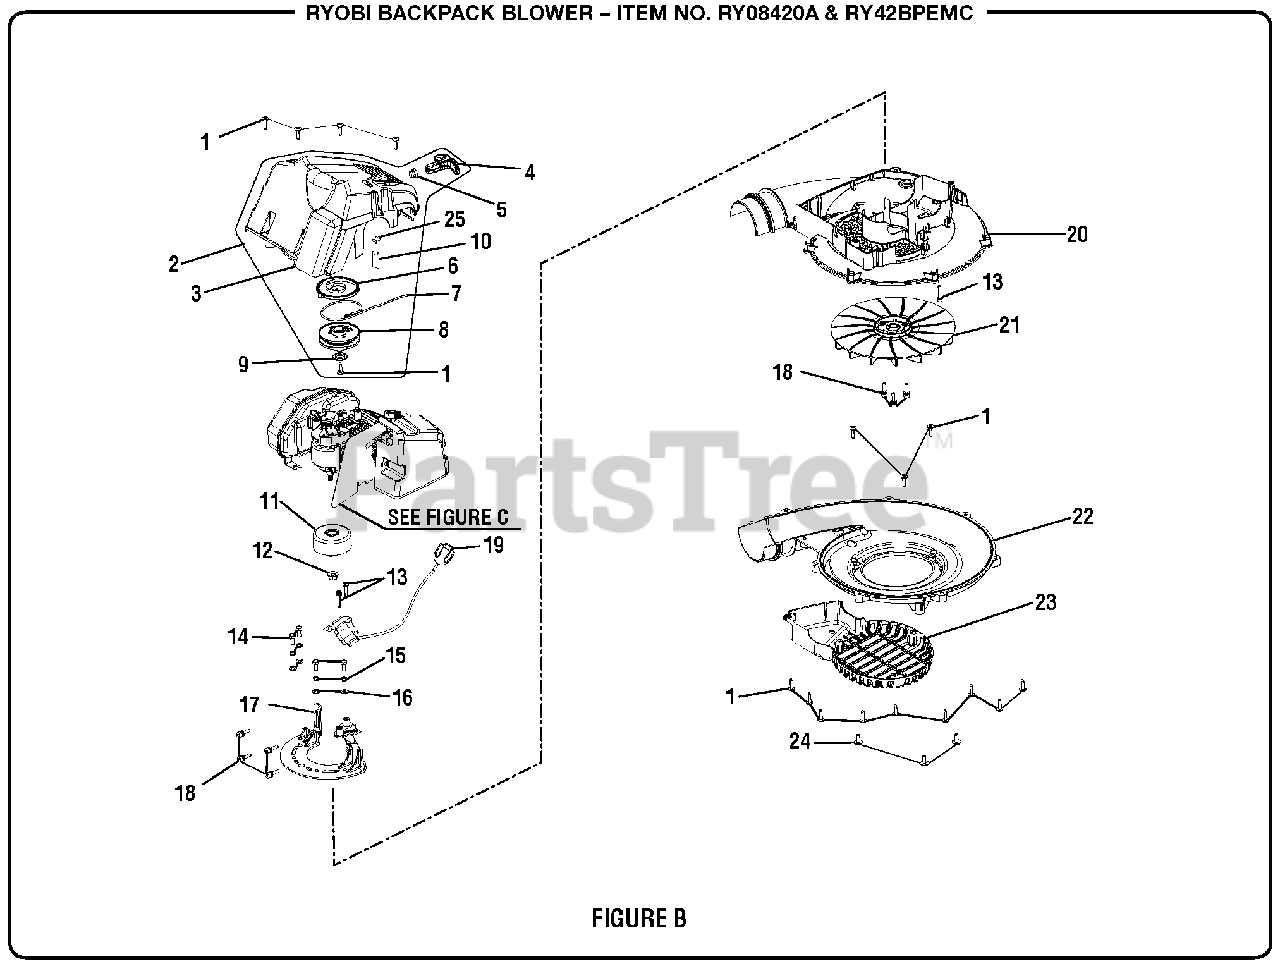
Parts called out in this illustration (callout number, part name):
1	Screw (10-14 x 19 mm, T-25 Torx)
2	Engine Cover w/Starter Assembly w/Labels
3	Engine Cover w/Heatshields, Eyelet & Labels
4	Starter Grip
6	Container Spring Assembly
7	Starter Rope
8	Solid Pulley
9	Starter Cap
10	Eyelet Support
12	Lock Nut (M8)
13	Screw (M5 x 25 mm, T-25 Torx)
14	Screw (M6 x 14 mm)
15	Spring Washer (ID6.4 x 1.6t)
16	Washer (OD12.9 x ID6.6 x 1.2t)
17	Engine Mount
18	Screw (M5 x 0.8 in., 20 Torx)
19	Ignition Module (RY08420A)
19	Ignition Module (RY42BPEMC)
20	Inner Volute w/Label
22	Outer Volute
23	Intake Grill
24	Screw (10-14 x 16 mm)
